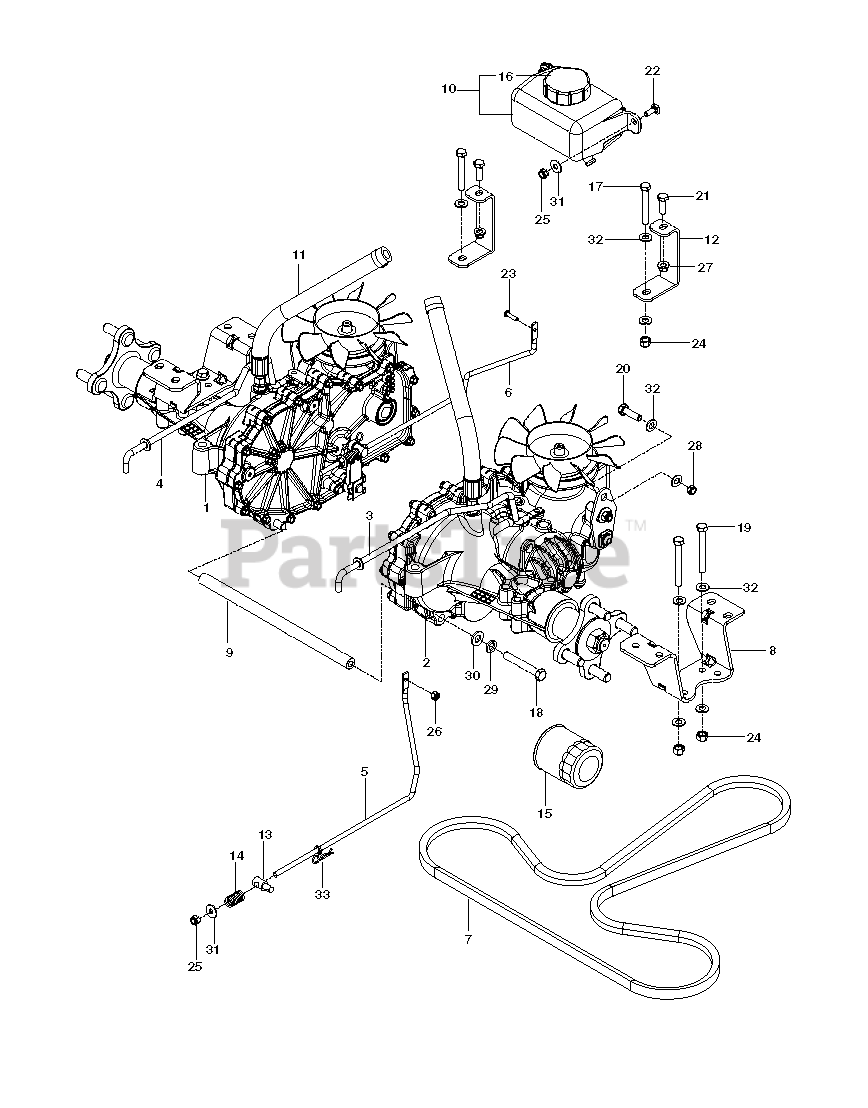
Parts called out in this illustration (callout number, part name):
1	HG_TRANS, ZT-2800 RT
2	HG_TRANS, ZT-2800 LEFT
3	ROD, BYPASS, RT
4	ROD, BYPASS, LT
5	LINKAGE, BRAKE RT
6	LINKAGE.BRAKE.LT
7	EZT HYDRO BELT
8	EZT MOUNT, REAR, BLACK
9	SPACER TUBE, EZT, 11.08
10	HG_EXPANSION TANK W/CAP
11	HOSE ASSY
12	SUPPORT FRT TRANS, BLK
13	BRAKE SWIVEL
15	HG_FILTER, ZT4800
17	CAPSCREW
18	HCS 3/8-16X2-1/4 LOC PATCH GR8
19	HCS 5/16C X 2-3/4
20	HCS 5/16C X 1
21	HCS 1/4C X 3/4 HCS
22	RHSNB 1/4C X 3/4
23	SCR #10-24 X 3/4
24	NUT 5/16 NYLOC
25	NUT 1/4-20 NYLOC
26	NUT 10-24 NYLOC
27	5/16-18 NYLOC FLANGE NUT
28	5/16-18 THIN PROF NY
29	SLW 3/8 STD
30	WASHER 3/8 SAE FLAT
31	WASHER 1/4 FLAT
32	FLAT WASHER 5/16 SAE
33	HAIRPIN #2
